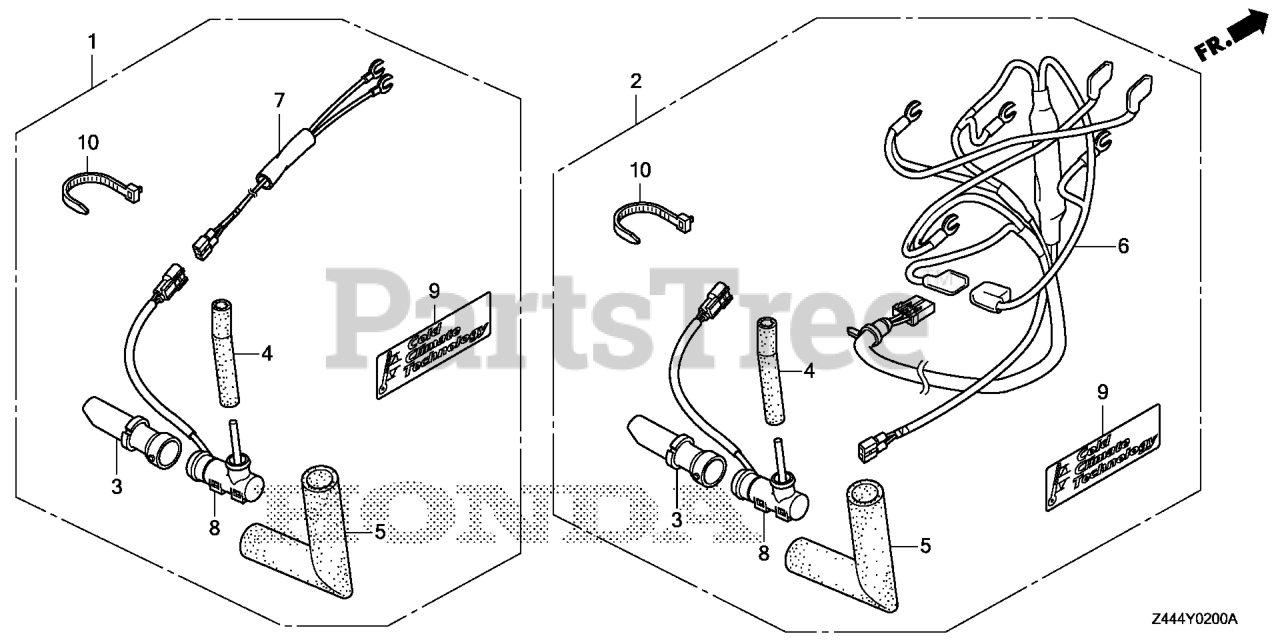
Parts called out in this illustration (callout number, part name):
1	HEATER KIT, BREATHER (A)
3	TUBE, BREATHER
4	TUBE B, BREATHER
5	INSULATOR L, BREATHER TUBE
7	SUB-WIRE ASSY.
8	HEATER ASSY., BREATHER (L)
9	MARK (CCT)
10	BAND, HARNESS (BLACK)
